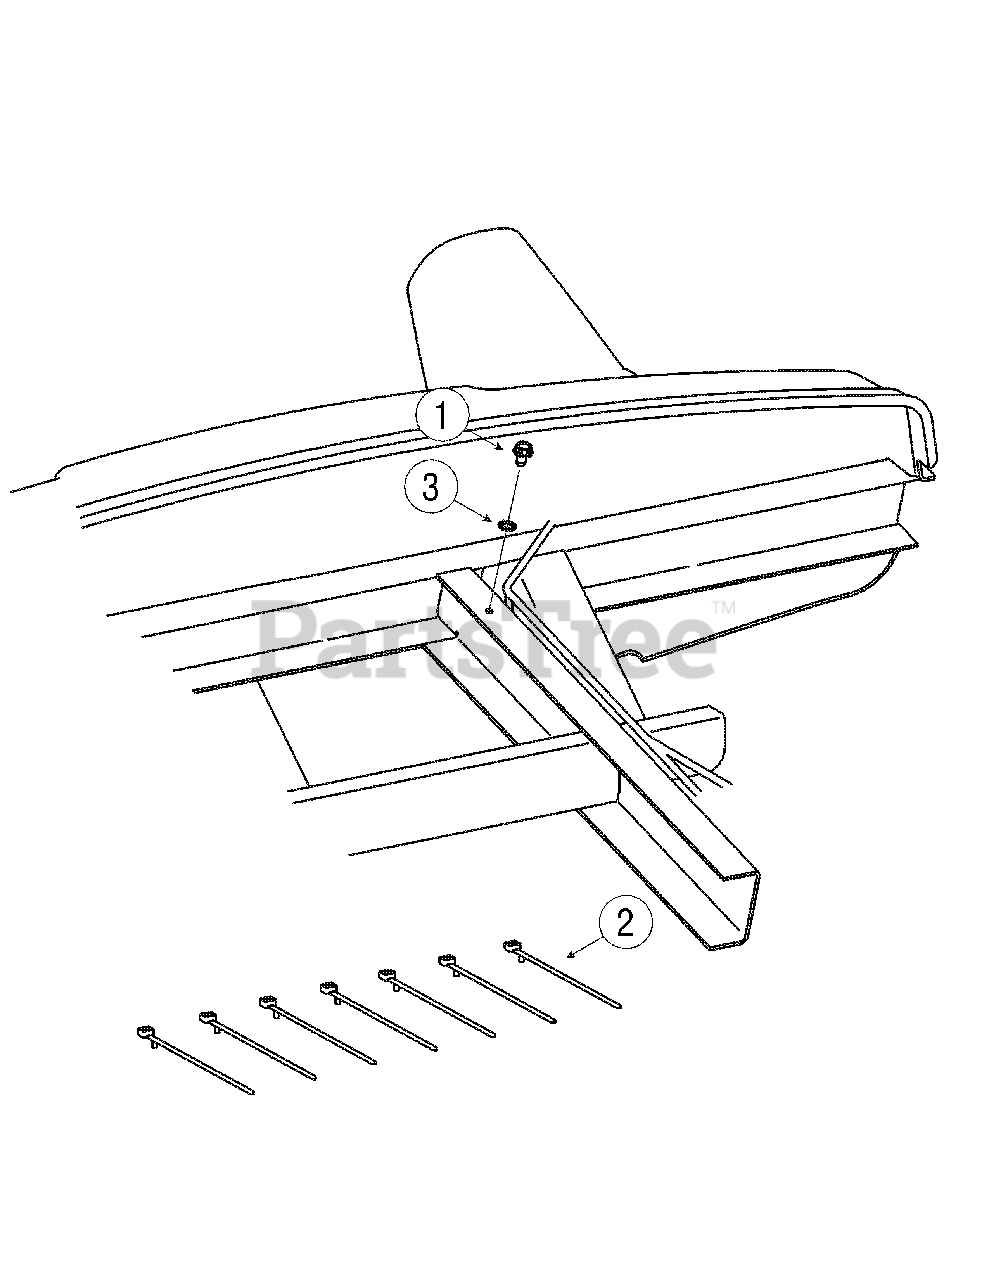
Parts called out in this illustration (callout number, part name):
1	Scr, tt, 5/16-18 x .500
2	Tie, Cable
3	Washer, Lock, 5/16
